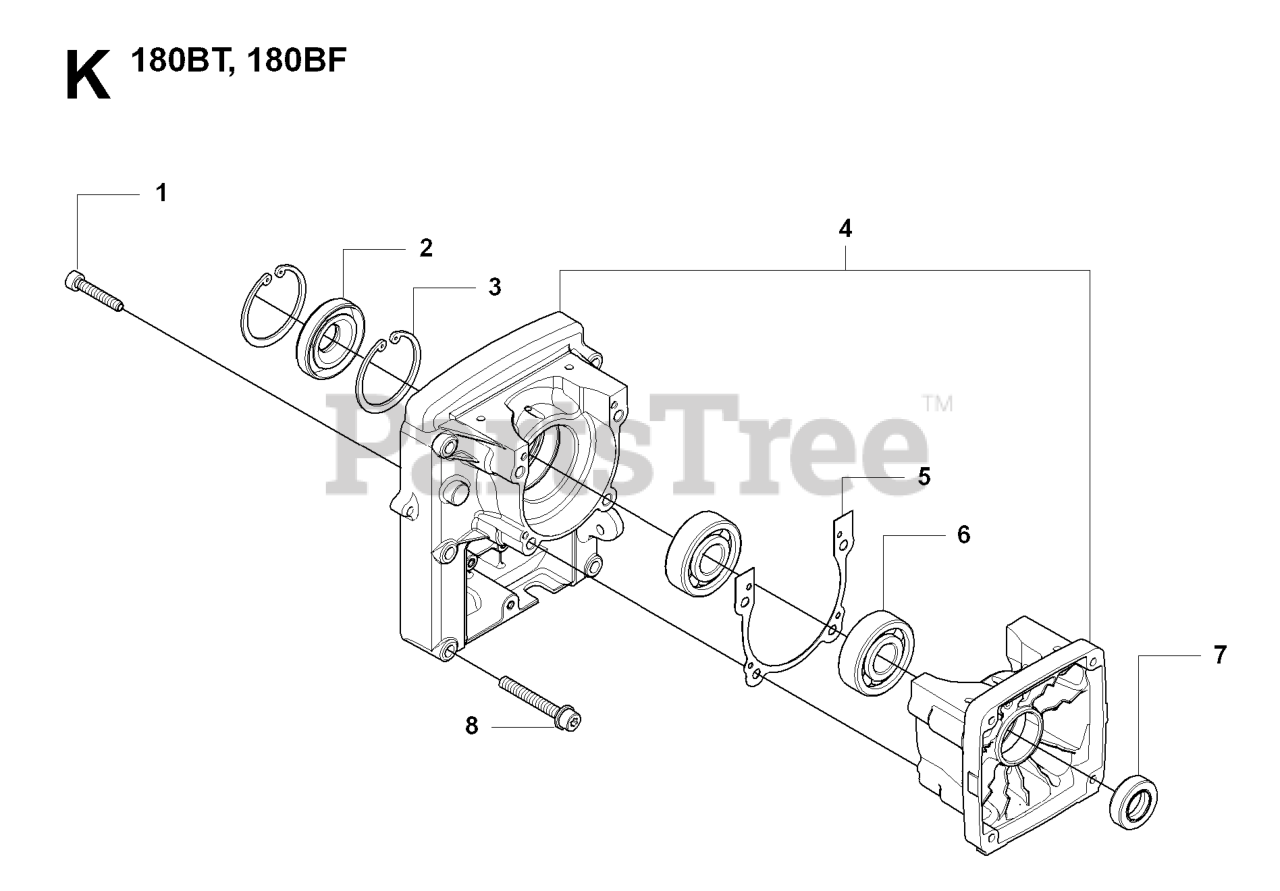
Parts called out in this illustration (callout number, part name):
1	BOLT
2	SEAL
3	SNAP RING
4	CRANKCASE-C
5	GASKET
6	BEARING
7	SEAL
